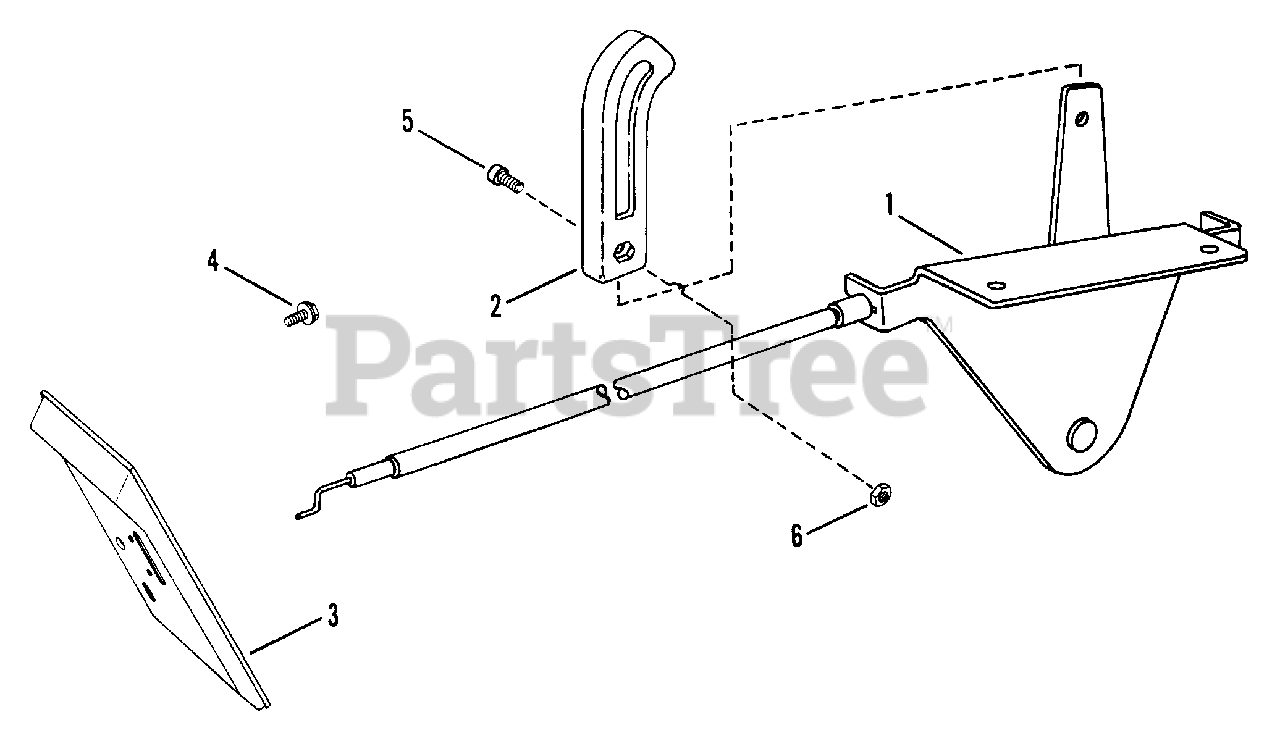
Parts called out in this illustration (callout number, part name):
1	CONTROL, Throttle
2	KNOB, Throttle Control
3	COVER, Dash Panel (Electric Start)
4	SCREW, #10-24 x 1/2" Hex Flange Self-Tapping
5	SCREW, #8-32 x 3/8" Rec. Fill. Hd.
6	NUT, #8-32 Hex
